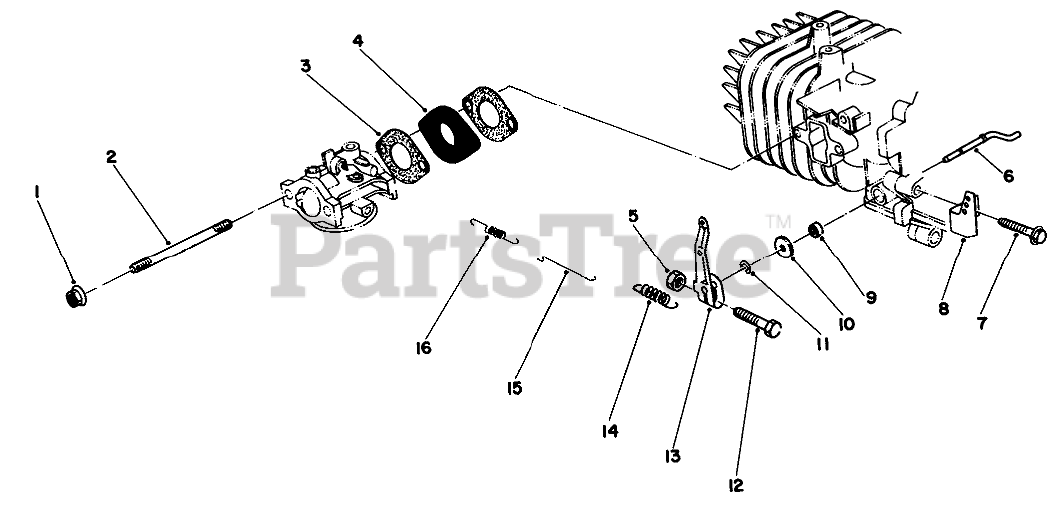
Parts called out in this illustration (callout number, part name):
1	M6 X 1 LOCKNUT
2	Stud-Bolt-Carburetor
3	GASKET-CARB
4	CARB. INSULATOR
6	Shaft-Govemor
8	Bracket-Governor Spring
9	SEAL-OIL
10	WASHER
11	E-RING
13	Lever-Throttle Control
14	SPRING
15	ROD-CARBURETOR
16	Spring-Governor
